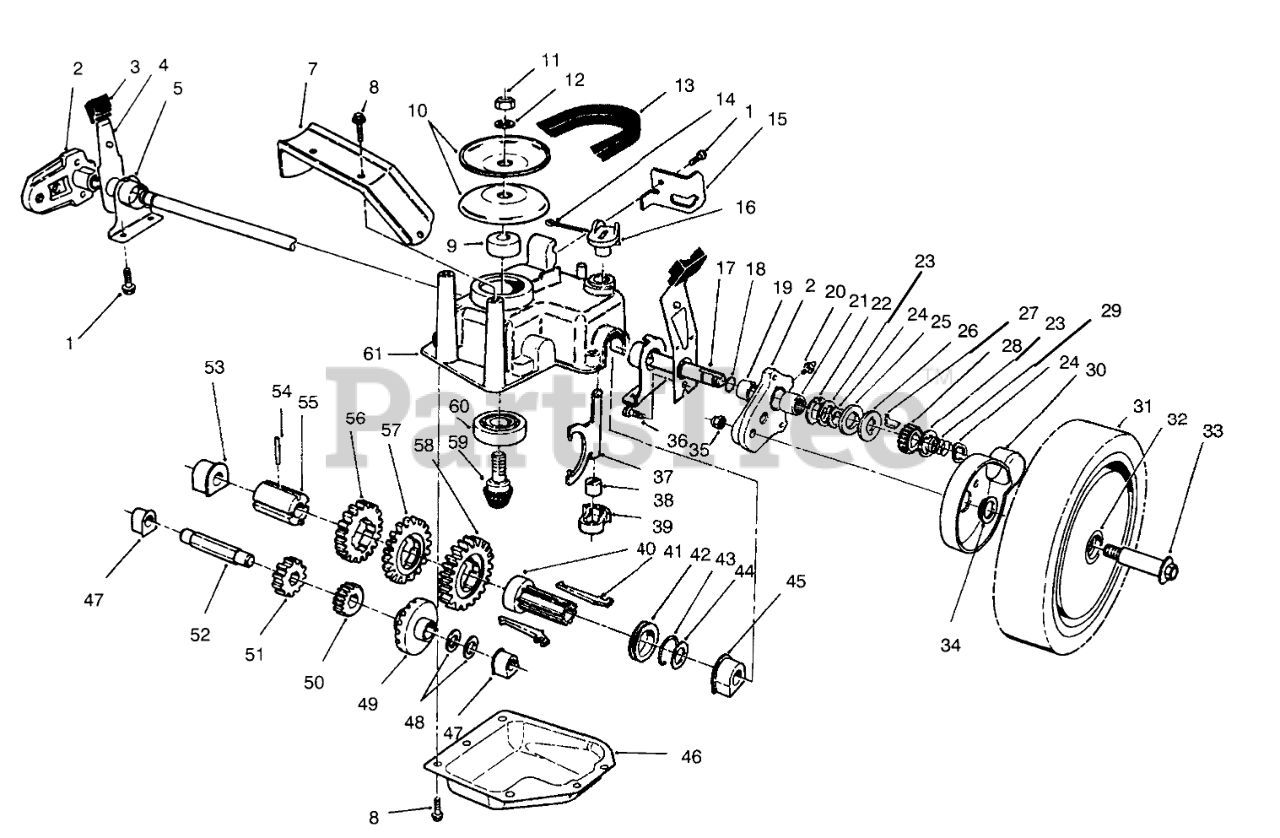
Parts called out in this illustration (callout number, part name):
1	SCREW-HWHTF
2	Pivot Arm Assembly (Incl. Ref. #19-21)
3	KNOB-ARM
4	SPRING ARM ASM
5	CAP-END
7	Bracket-BeltGuide
8	SCREW-HWHTF
9	SPACER
10	Pulley Half
11	NUT-HEX
12	WASHER-FLAT
13	V-BELT
14	PIN-COTTER
15	RETAINER-CABLE
16	LEVER-SHIFT
17	SHAFT-OUTPUT
18	O-RING
19	BUSHING
20	FITTING-GREASE
21	BEARING-ROLLER
22	WASHER-ARM, PIVOT
23	WASHER-THRUST, KEYED
24	RING-CLIP, LOCKING
25	RING-FRICTION
26	WASHER-CLUTCH
27	KEY-ROCKING, LH
28	GEAR-PINION
29	SPRING-COMPRESSION
30	COVER-WHEEL
31	Wheel Tire & Gear Assy.(Incl. Ref. #32)
32	BUSHING
33	WHEEL BOLT
34	SPACER-COVER, WHEEL
35	NUT-LOCK
36	SCREW-HSH, THREAD FORMING
37	YOKE-SHIFT
38	BUSHING-YOKE
39	RETAINER-FORK, SHIFT
40	SLEEVE-KEY, SHIFT
41	KEY-SHIFT
42	COLLAR-SHIFT
43	CLIP-SPRING
44	WASHER-PLAIN
45	BUSHING-OUTPUT
46	Cover-Gearcase
47	BUSHING
48	WASHER-THRUST
49	Gear-Bevel
50	PINION-20T
51	PINION-25T
52	SHAFT-INTERMEDIATE
53	BUSHING
54	PIN-SPRING
55	SLEEVE-GEAR
56	GEAR-39T
57	GEAR-44T
58	GEAR-49T
59	Gear-Pinion
60	BEARING-BALL
61	CASE-GEAR, UPPER
